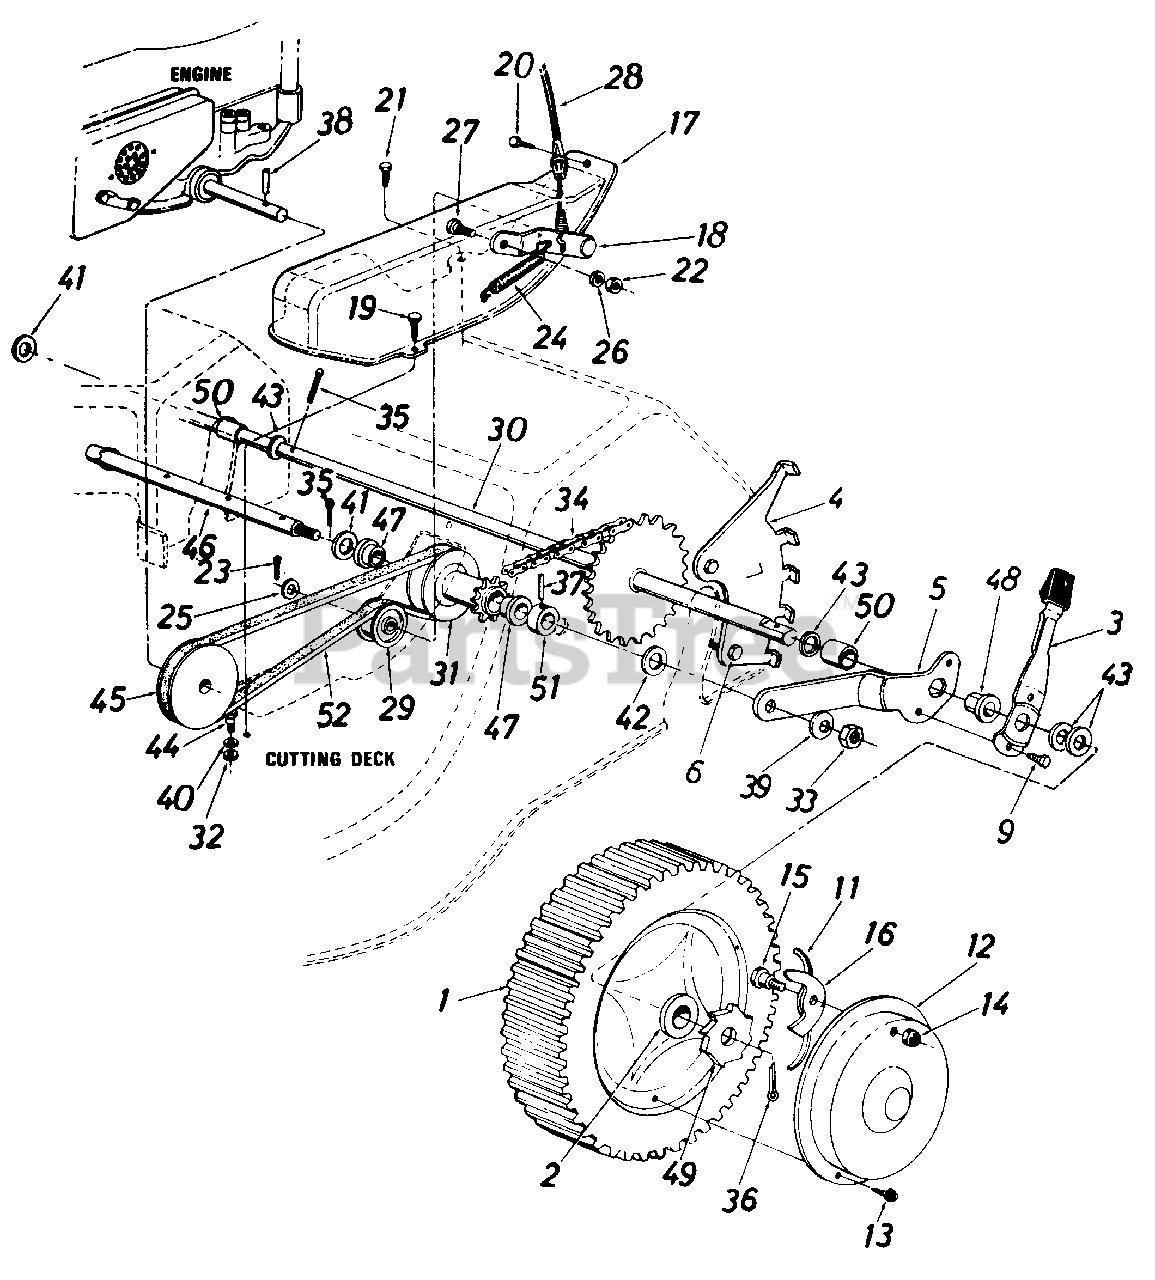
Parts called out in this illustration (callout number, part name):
1	Wheel Ass y. Comp. 8.0 x
2	Flange Brg. 1/2" I.D.
3	Spring Lever w/Knob
4	Index Plate Ass'y. L.H.
5	Pivot Brkt. L.H.
6	Hex Wash. Hd. Tap Scr. 1/4 x.62"
9	Hex B-Tap Scr. 1/4 x .38"
11	Nylon Spring
12	Hub Cap
13	Pan Hd. Tap Scr. #12 x .50"
14	Hex Ins. L-Nut 1/4-20 Thd.
15	Shld. Bolt .342" Dia. x .268
16	Pawl
17	Belt Cover
18	Idler Bracket Ass'y.
19	Hex Wash. Hd. Self-Tap Scr. 1/4-20 x .50" Lg.
20	Hex Drilling Scr. #10 x .50"
21	Hex TT-Tap Scr. 1/4-20 x .75"
22	Hex Nut 1/4-20 Thd.
23	Cotter Pin 1/8" Dia. x 1.00"
24	Extension Spring .33" O.D. x 1.12" Lg.
25	Fl-Wash. .531" I.D. x .930" 0. D.
26	L-Wash. 1/4" I.D.
27	Shld. Bolt .375" Dia. x .181
28	Clutch Cable 50"
29	Flat Idler Plastic
30	Rear Shatt Ass'y.
31	Pulley w/9 Tooth Sprocket Ass'y.
32	Hex Nut 5/16-18 Thd.
33	Hex Jam Nut 3/8-16 Thd.
34	#48 Chain 1/2" Pitch x 31 Links
35	Cotter Pin 8/32" Dia. x 1.00"
36	Cotter Pin 1/8".Dia. x 1.00"
37	Spring Pin Spir. 3/16" Dia. x 1.00" Lg.
38	Spring Pin Spir. 3/16" Dia. x 1.50" Lg.
39	Bell-Wash. .400" I.D. x .88" O.D.
40	L-Wash. 5/16" I.D.
41	Fl-Wash. .531" I.D. x .930" O.D.
42	Bell-Wash. .400" I.D. x 1.13" 0. D.
43	Fl-Wash. .510" I.D. x 1.0" O.D
44	Shld. Bolt .437" Dia. x .470"
45	Engine Pulley
46	Pulley Shaft
47	Flange Brg. .506" I.D. Plastic
48	Hex Flange Brg. .506" I.D. Plastic
49	Ratchet
50	Spacer.765" I.D. x .89" O.D. x.960" Lg.
51	Spacer .505" I.D. x .88" O.D. x.44" Lg.
52	"V"-Belt 1/2 " x 31 " Lg.
